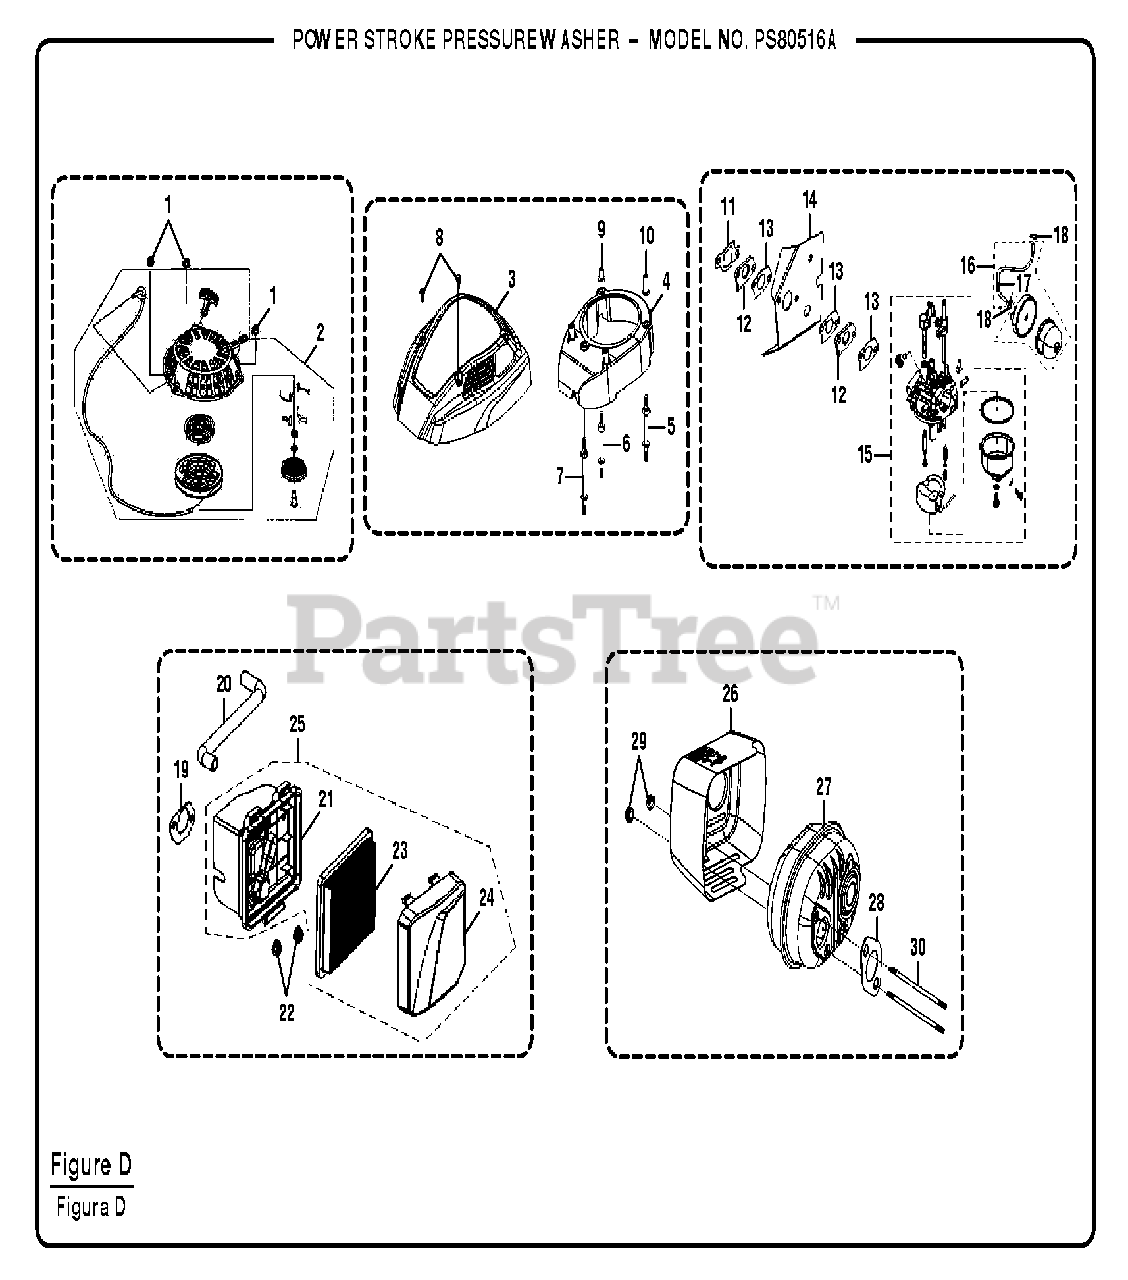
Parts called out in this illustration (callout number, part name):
2	Recoil Starter Assembly
11	Insulator Plate Gasket
12	Carburetor Insulator Plate
13	Carburetor Gasket
14	Carburetor Insulator Gasket
15	Carburetor Assembly
19	Air Cleaner Gasket
21	Air Cleaner Case
23	Air Clean Element Assembly
24	Air Cleaner Cover
26	Muffler Outer Cover
27	Muffler Assembly
28	Exhaust Outlet Gasket
